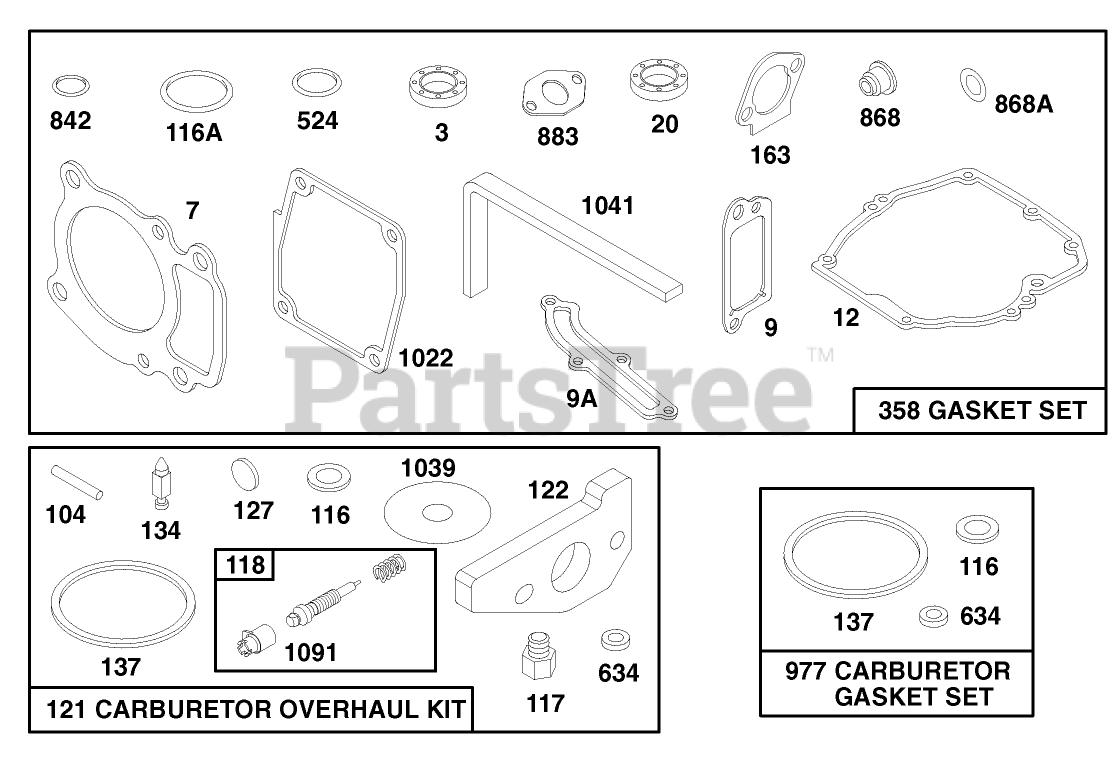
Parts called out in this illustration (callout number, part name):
7	CYLINDER HEAD GASKET
12	ENGINE BASE GASKET
20	SEAL-OIL
116	SEALING GASKET
116A	O RING SEAL
121	KIT-CARBURETOR OVERHAUL
122	ADAPTER ASSEMBLY
134	VALVE-FLOAT
137	FLOAT BOWL GASKET
163	AIR CLEANER GASKET
358	GASKET SET
524	O-RING
842	O-RING
977	CARBURATOR GASKET SET
1022	ROCKER COVER GASKET
1039	FLOAT LIMITER
1091	CAP - LIMITER
